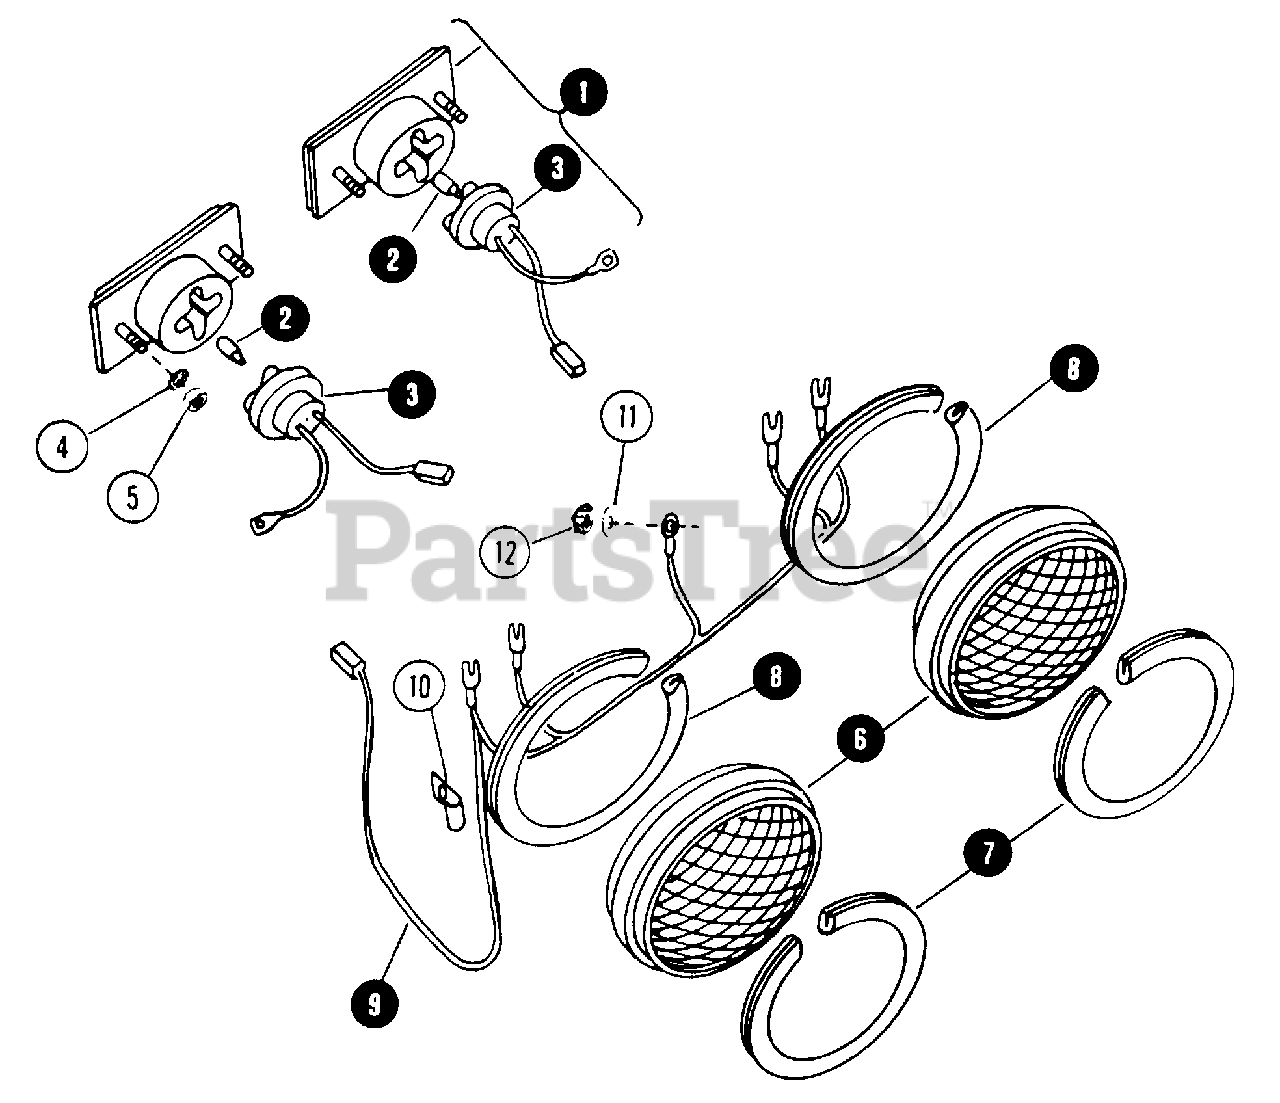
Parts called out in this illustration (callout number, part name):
1	TAIL, LIGHT ASSY.
2	BULB, TAIL LIGHT
3	SOCKET, TAIL LIGHT TERMINAL
4	WASHER, #10 EXTERNAL TOOTH LOCK
5	NUT, #10-32 (SPECIAL)
6	HEADLAMP, SEALED BEAM
7	MOLDING, OUTSIDE HEADLAMP
8	MOLDING, INSIDE HEADLAMP
9	HARNESS, HEADLAMP WIRING
10	CLIP, HARNESS TO HOOD
11	WASHER, 1/4 FLAT
12	NUT, 1/4C HEX LOCK
